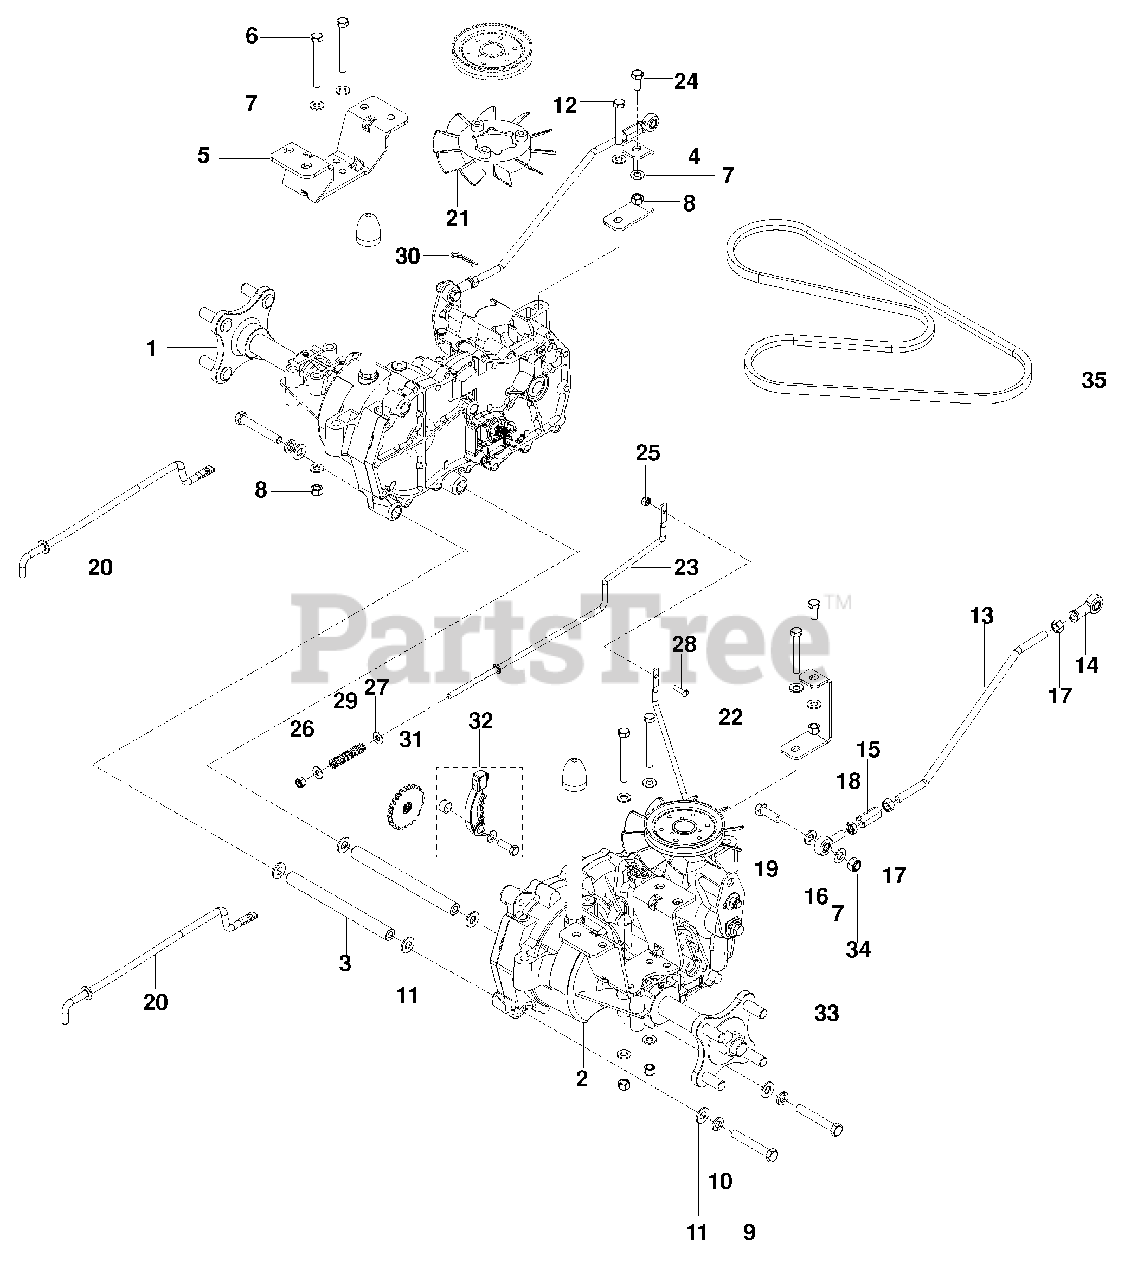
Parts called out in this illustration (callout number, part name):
3	SPACER TUBE
4	SUPPORT, EZT FRT
5	MOUNT, EZT RR BLK
6	HCS 5/16-18 x 2 3/4
7	WASHER 5/16 SAE FLT
8	NUT 5/16-18 HEX NYLOC
9	HCS 3/8-16 x 21/2
10	WASHER 3/8 SPLT LK
11	WASHER 3/8 SAE FLT
12	HCS 5/16-18 x 2 1/4
13	ROD, MOTION CONTROL
14	ROD END RT
15	COUPLER, ROD END
16	ROD END MALE LT
17	NUT 5/16-24 HEX
18	NUT 5/16-24 HEX JAM LH
19	HCS 5/16-18 x 1
20	LINK ARM, BYPASS
21	BLADE, FAN
22	ROD, EZT BRAKE LT
23	ROD, EZT BRAKE RT
24	HCS 5/16-18 x 3/4
25	NUT 10-24 HEX NYLOC
26	NUT 1/4-20 HEX NYLOC
27	WASHER 1/4 SAE FLT
28	SCREW 10-24 x 3/4 SLTD RD
29	SPRING, BRAKE ROD
30	HAIRPIN, COTTER
31	COG, BRAKE DISC
32	BRAKE ARM KIT
33	HUB KIT
34	NUT 5/16-18 NYLOC INSERT
